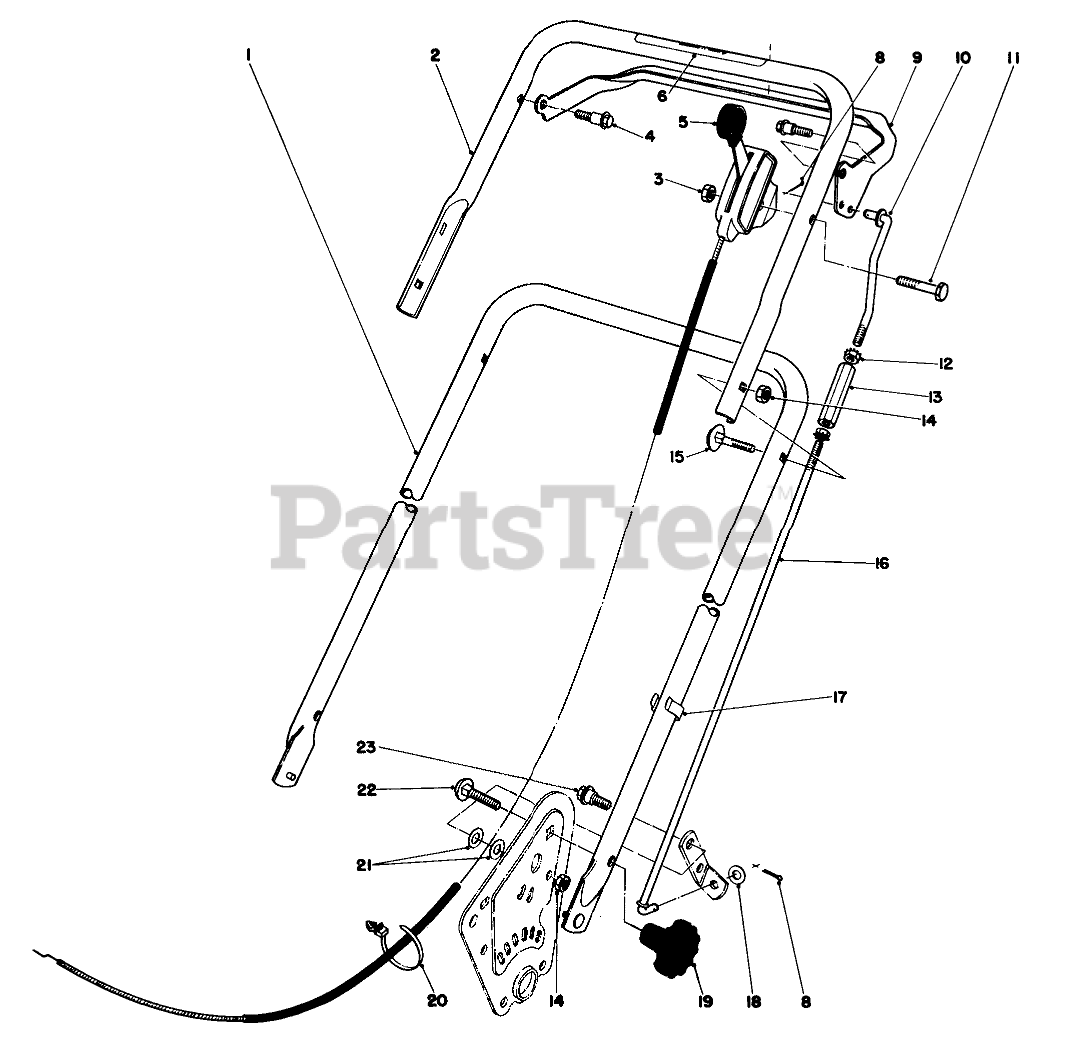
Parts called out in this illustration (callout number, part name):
1	Lower Handle
2	Upper Handle
3	NUT-LOCK
4	Shoulder Bolt
5	Throttle Control
6	Danger-Decal
8	PIN-COTTER
9	Squeeze Lever
10	CONTROL ROD LINK
11	SCREW-HH
12	NUT-KEPS
13	CONTROL ROD SLEEVE
14	Nut
15	HANDLE SCREW
16	CUTTER CONTROL ROD
18	WASHER-FLAT
20	TIE-MOUNT, PUSH
21	WASHER-FLAT
22	BOLT-CARR
23	SCREW-SHOULDER
